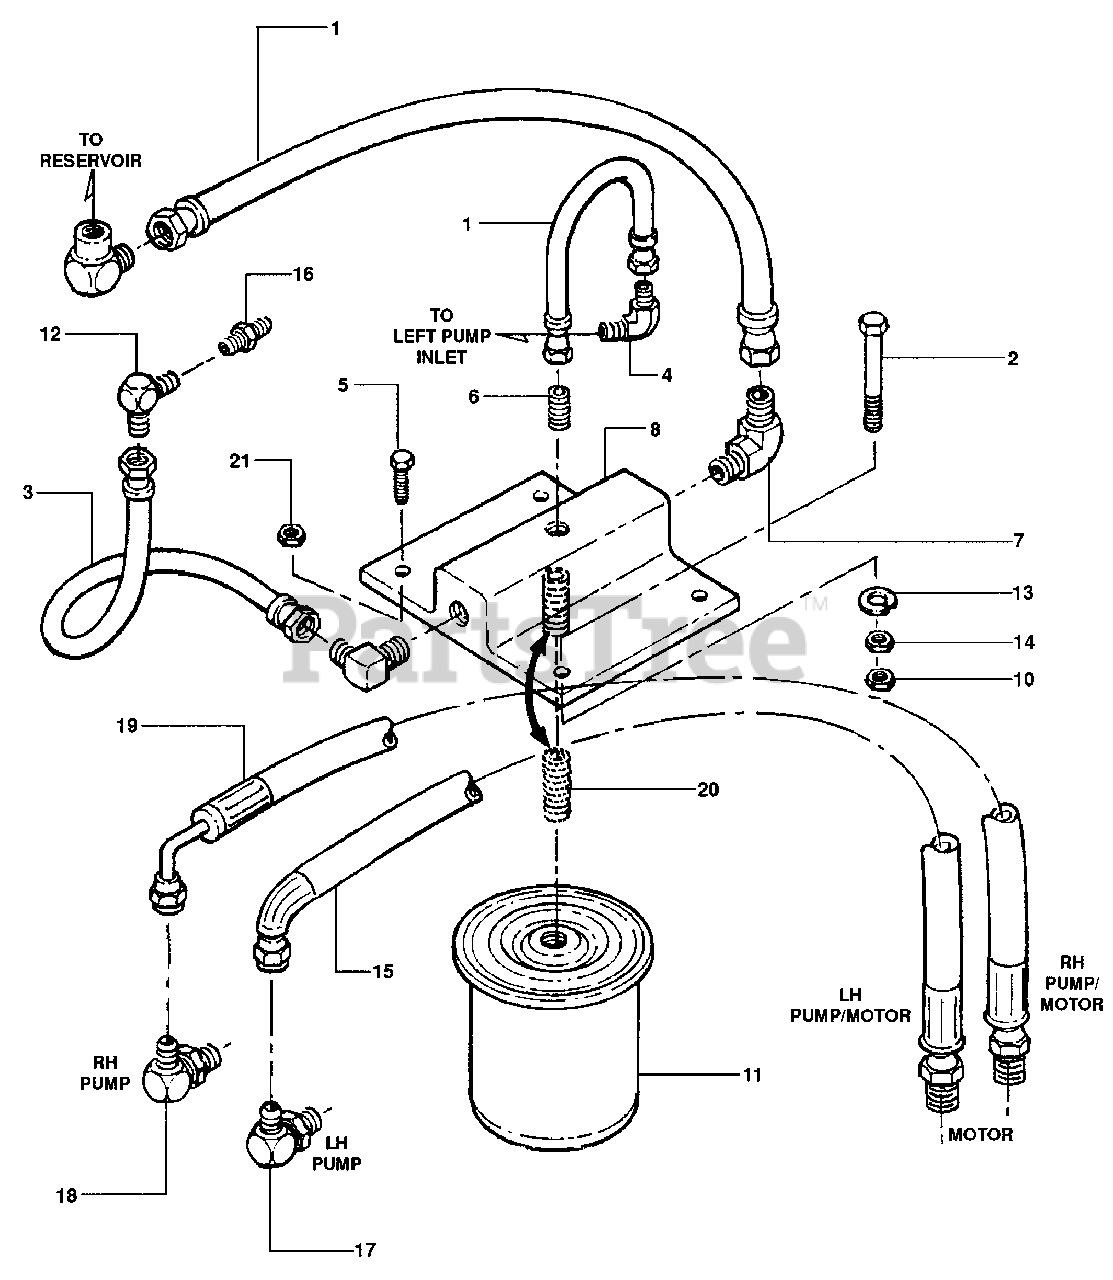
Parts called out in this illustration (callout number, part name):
1	HOSE, 1/2 X 16" Long
2	SCREW, 3/8-16 X 3-1/2"
3	HOSE, 9" Long
4	FITTING, 90° - "O"-Ring
5	SCREW, 5/16-18 X 1"
6	FITTING, Straight
7	FITTING, 90°.
8	OIL FILTER MOUNT
10	NUT, 3/8-16 Nyloc
11	OIL FILTER
13	WASHER, 3/8 Lock
14	NUT, 3/8-16
15	HOSE, PUMP/MOTOR, Left Hand
16	FITTING, Straight with "O"-Ring
17	FITTING, 45° with "O"-Ring
18	FITTING, 90° with "O"-Ring
19	HOSE, PUMP/MOTOR, Right Hand
20	FITTING, Straight 1", #12 Thread
21	NUT, 5/16-18
